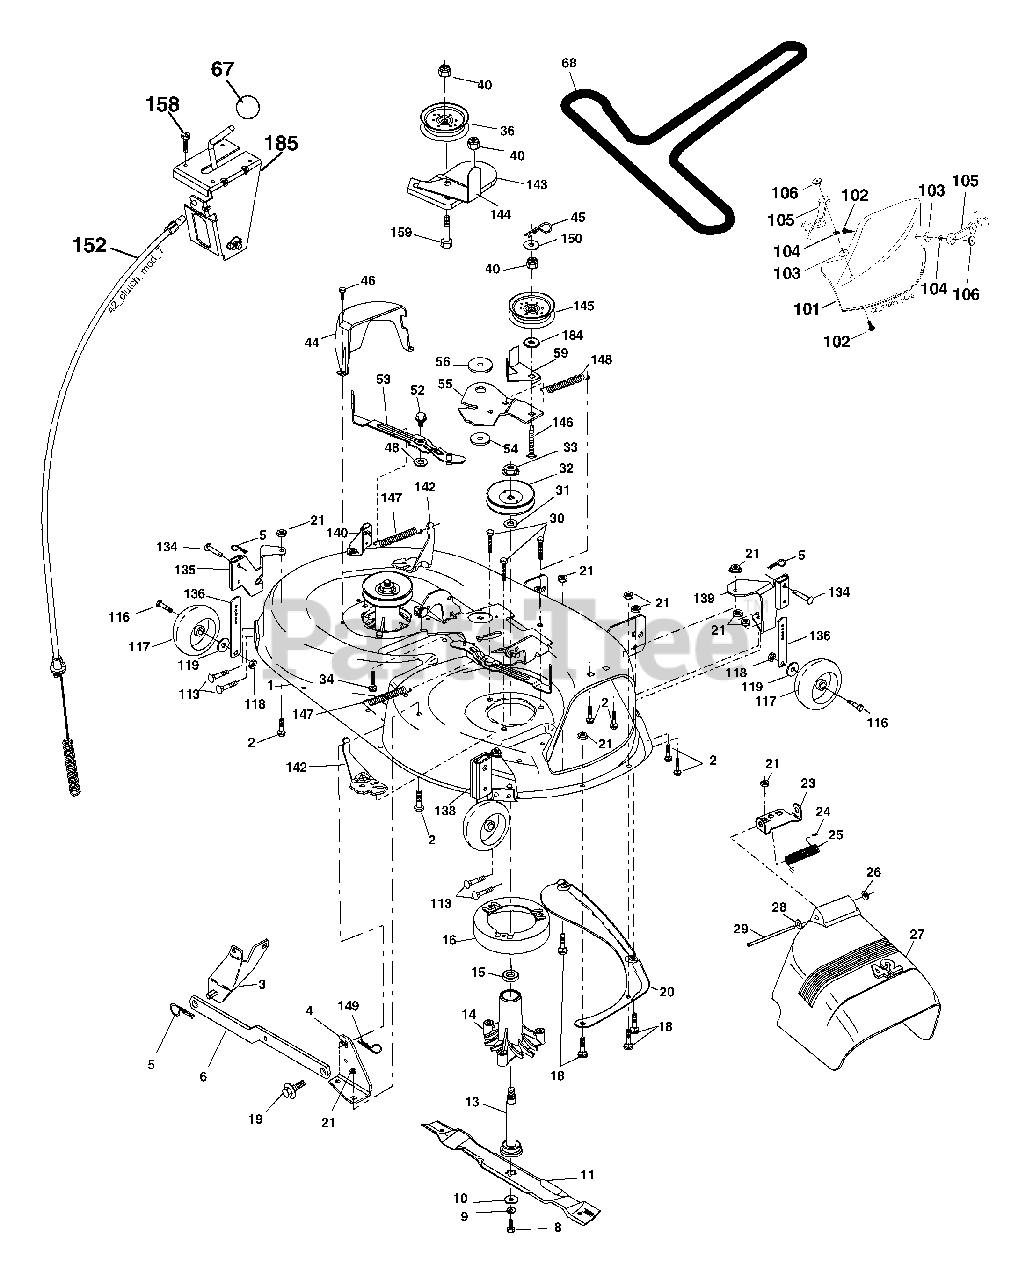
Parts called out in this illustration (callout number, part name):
1	Mower Deck Assembly, 42"
2	Bolt
3	Bracket Asm Fr. Sway Bar 3/42
4	Bracket Asm Deck 42" Sway Bar
5	Retainer Spring
6	Bar Sway Deck
8	Bolt 3/8-24 x 1.25 Gr. 8 patched
9	Washer, Lock
10	Washer, Hardened
11	Blade, Mulching 42" Std
11	Blade Mulching 42" Premium
11	Blade Mower 42" Hi-Lift
13	Shaft Assembly, Mandrel, Vented
14	Housing, Mandrel, Vented
15	Bearing, Ball, Mandrel
16	Stripper, Mandrel Deck
18	Bolt, Carriage 5/16-18 x 5/8
19	Bolt, Shoulder
20	Baffle, Vortex
21	Nut
23	Bracket, Deflector Mower 42"
24	Cap, Sleeve 80 x 112 Blk Mower
25	Spring, Torsion, Deflector 2 52
26	Nut, Push Phos & Oil
27	Shield, Deflector 42" Blk
28	Washer 11/32 x 5/8 x 16 Ga.
29	Rod, Hinge 42" 6 75 W/G
30	Screw Thdrol
31	Washer, Spacer Mower Vented
32	Pulley, Mandrel
33	Nut, Toplock
34	Bolt Carr SH 3/8-16 x 1-1/2 Gr.5
36	Pulley, Idler, Flat
40	Nut Lock 3/8-16
44	Guard, Mandrel, LH
45	Retainer
46	Screw, Thdrol 1/4-20 x 5/8 T
48	Washer, Hardened
52	Bolt, Shoulder 5/16-18 unc
53	Arm Assembly, Pad, Brake
54	Washer, Hardened
55	Arm, Idler
56	Spacer, Retainer
59	Guard TUV Idler
67	Knob Round
68	V-Belt, 42" Mower
101	Mulcher Cover
102	Screw, Pan Hd Phillip 10-24 x 5/8
103	Washer, Flat
104	Washer, Lock
105	Latch Assembly
106	Nut, Weld
113	Screw 5/16-18 x 3/4
116	Bolt, Shoulder
117	Wheel, Gauge
118	Nut Centerlock 3/8-16
119	Washer 3/8 x 7/8 x 14 Ga.
134	Pin Head Rivet
135	Bracket Asm. Whl Ga. R LH
136	Bar Adjusting Gauge Wheel
138	Bracket Asm Whl Ga. R RH
139	Bracket Asm. Whl Ga. F RH
140	Bracket Asm Whl Ga. F LH
142	Arm Spring Brake Mower
143	Bracket Arm Idler 42"
144	Keeper Belt 42" Clutch Cable
145	Pulley Idler Flat
146	Bolt Carriage Idler
147	Spring Extension
148	Spring Return Idler
149	Retainer Spring Yellow
150	Washer 9/32 x 3/4 x 10 Ga.
152	Clutch Cable 42"
158	Screw Hex Thd Cut 1/4-20 x 1/2
159	Bolt Rdhd Sqn 3/8-16 unc x 1-3/4
184	Washer 13/32 x 7/8 x 10 Ga.
185	Head Asm Cable Clutch
